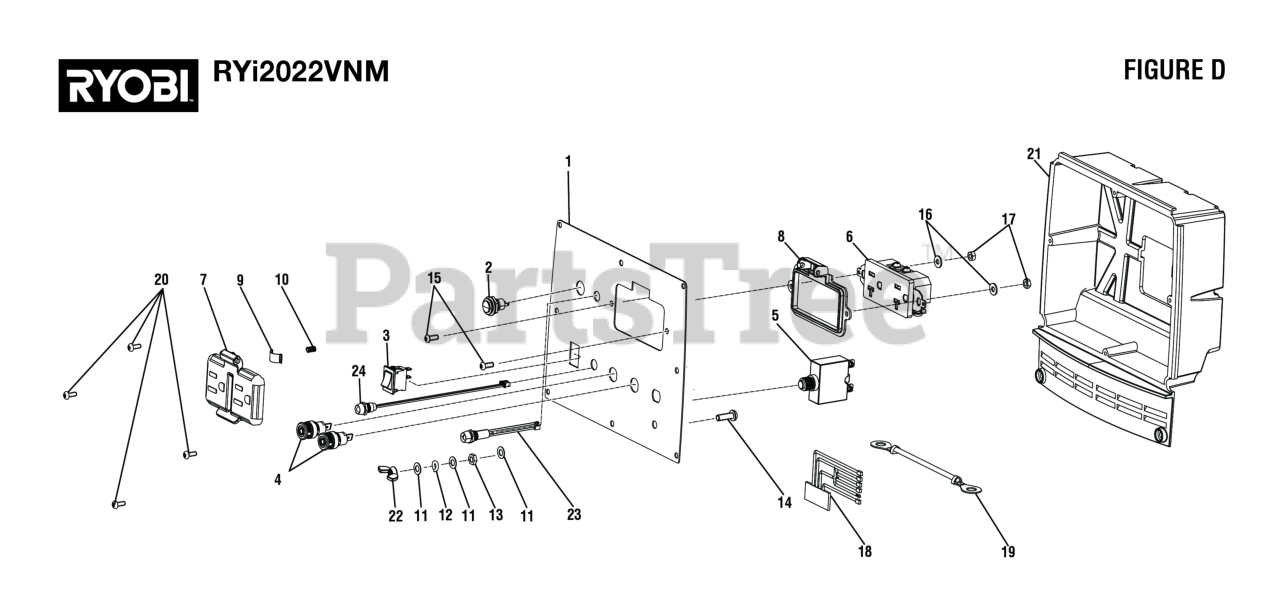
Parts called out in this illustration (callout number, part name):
1	Front Cover
2	Reset Button
3	Auto Idle Switch
4	Connector (Black)
5	Circuit Breaker (20 Amp, 125 Volt)
6	120 Volt Duplex Receptacle (BM903611)
7	Receptacle Cover (Front)
8	Fixed Outlet Cover
10	Governor Damping Spring
11	Flat Washer (OD10 x ID5.3 x 0.5t)
12	Lock Washer (OD9 x ID5 x 1.3t)
13	Hex Nut (M5)
14	Screw (M5 x 16 mm, Phillips Pan Hd.)
15	Bolt (M4 x 10 mm, T15 Torx Drive Hd.)
16	Flat Washer (OD10 x 42 x 1t)
17	Flange Nut (M4)
18	Internal Wire Assembly
19	Ground Wire
20	Screw (#6-20 x 3/8 in., T15 Torx Pan Hd.)
21	Electrical Panel Housing
22	Wing Nut (M5)
23	Indicator (Red LED 3.3V-4mA)
24	CO Indicator
